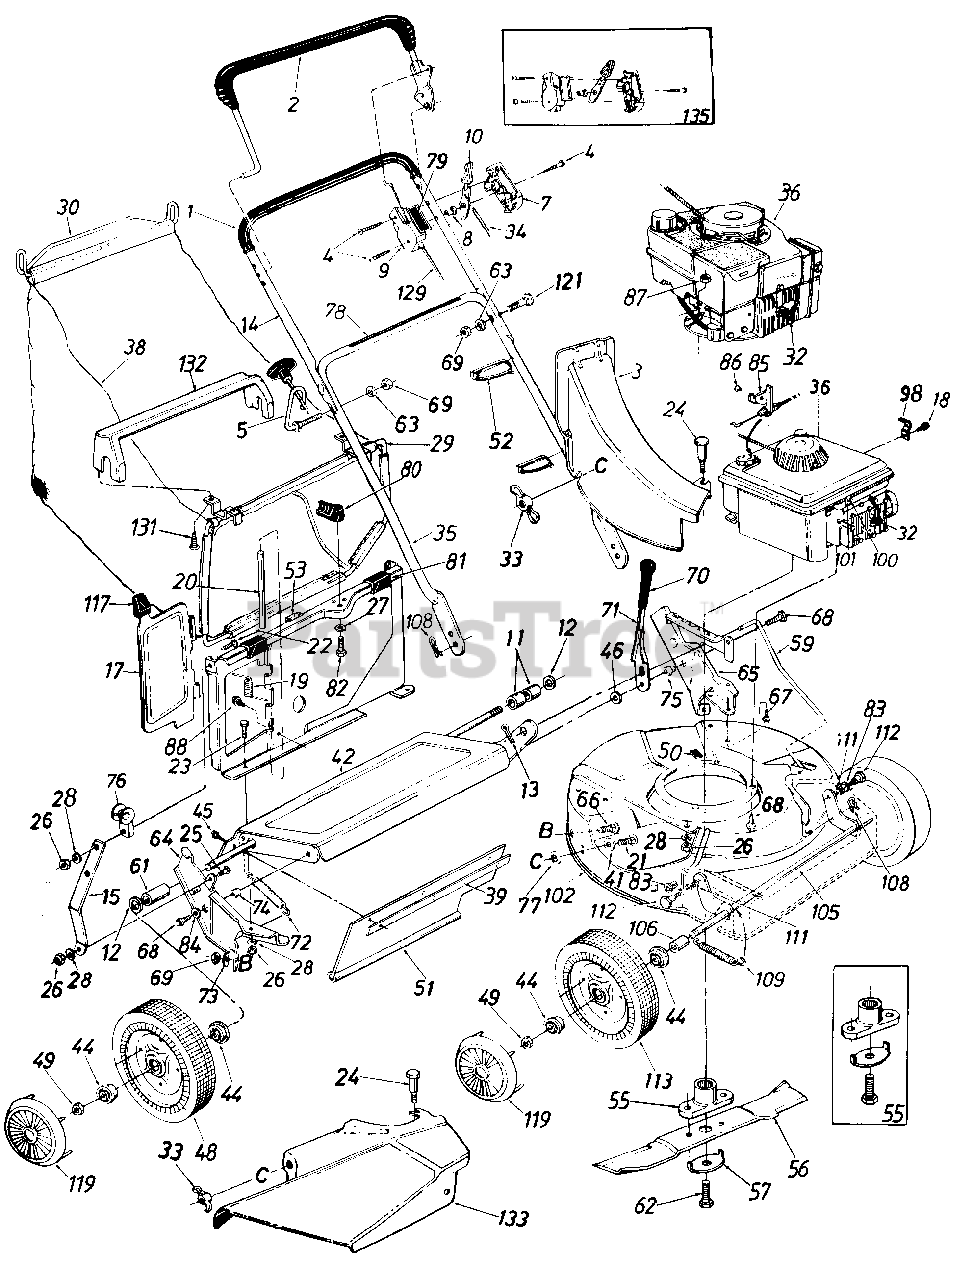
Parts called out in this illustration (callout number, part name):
1	Foam Grip
2	Control Handle Ass'y.-L.H.
3	Top Discharge Chute Assy.
4	Truss Mach. Scr. #12 x 1.50" Lg.
5	Rope Guide Bolt
7	Control Panel Half
8	Control Disc Pin
9	Clutch Panel Half
10	Throttle Control Lever
11	Spacer. 526" I.D. x .690" O.D. x 640" Lg.
12	Fl-Wash. .510" I.D. x .75"
13	Cotter Pin 3/32" Dia. x .75"*
14	Upper Handle-Chrome
15	Panel Support Brkt.
16	Top Catcher Panel Ass y.
17	Top Discharge Door
18	Hex B-Tap Scr. #10 x .38"
19	Torsion Spring
20	Pivot Pin
21	Carriage Bolt 1/4-20 x .62"*
22	Truss Mach. Scr. 1/4-20 x .75" Lg.
23	Hex Bolt 1/4-20 x .50" Lg.
24	Shoulder Bolt .312 Dia. x .18 Lg. Special
25	Hex Bolt 1/4-20 x .62" Lg.*
26	Hex Nut 1/4-20 Thd.*
27	Spring Wash. .32" I.D.
28	L-Wash. 1/4" I.D.*
29	Front Grass Catcher Frame
30	Upper Bag Handle
32	Spark Plug Insulator
33	Wing Nut w/Washer
34	Throttle Control Wire-55"
35	Lower Handle-Chrome
36	Engine
38	21" Top Discharge Grass Bag-Black
39	Retaining Strip
41	Fl-Wash. .344" I.D. x .62"
42	Rear Axle Ass'y.
44	Flange Ball Bearing 1/2" I.D.
45	Hex AB-Tap Scr. 1/4 x .62"
46	Fl-Wash. .38" I.D. x 1.0"
48	Wheel Ass'y.-Comp.
49	Hex L-Nut 1/2-20 Thd.
51	Rear Flap 3.75" x 17.30" Lg.
52	Cable Tie
53	Foam Strip 1" Lg.
55	Blade Adapter Kit-Keyed
56	21" Blade
57	Blade Bell-Wash. .44" I.D. x 2.38"
59	Height Adj. Rod. 19.42" Lg.
61	Sleeve .526" I.D. x .69"
62	Hex Bolt 7/16-20 x 1.5" Lg.
63	L-Wash. 5/16" I.D.*
64	R.H. Handle Wheel Brkt. Ass'y.
65	L.H. Handle Wheel Brkt. Ass'y.
66	Carriage Bolt 5/16-18 x .62"
67	Hex Wash. Hd. B-Tap Scr. 5/1 6-1 8
68	Hex Wash. Hd. TT-Tap Scr. 3/8-1 6
69	Hex Nut 5/16-18 Thd.*
71	Height Adj. Lever
72	Extension Spring 3.8" Lg.
73	Bell-Wash. 5/16" I.D.
74	Spacer .385" I.D. x .502" O.D. x .270" Lg.
75	Shld. Spacer .500" Dia.
76	Rope Guide
77	Bolt Retainer 1/4 x .50" O.D.
78	Instruction Label
79	Control Label
80	Grass Catcher Locking Knob
81	Panel Clip
82	Hex Tap Scr. 1/4-20 x .75" Lg.
83	Flanged Nyliner Br,o.
84	Fl-Wash. .531" I.D. x 1.25"
85	Cable Bracket
86	Pop Rivet .156" Dia.
87	Hex Nut 3/8-16 Thd.
88	Hex B-Tap Scr. #10 x .38"
98	Cable Clamp
100	Hex B-Tap Scr. #10 x .62"
101	Cable Clamp
102	21" Deck Ass'y.
105	Front Axle Ass'y.
106	Sleeve .526" I.D. x .690" O.D. x .880" Lg.
108	Intern. Cotter Pin 5/16" Dia.
109	Extension Spring 3.2" Lg.
111	Intern. L-Wash. 3/8 I.D.
112	Shld. Bolt .575" Dia. x .42"
113	Wheel Ass'y. Comp.
117	Door Grip
119	Hub Cap
121	Curved Carr. Bolt 5/16-18 x 1.38" Lg.
129	Control Cable-55" Lg.
131	Hex AB-Tap Scr. #12 x 1.25" Lg.
132	Bag Handle
133	Side Chute Deflector Ass'y.
135	Kit-Control Housing Comp.
